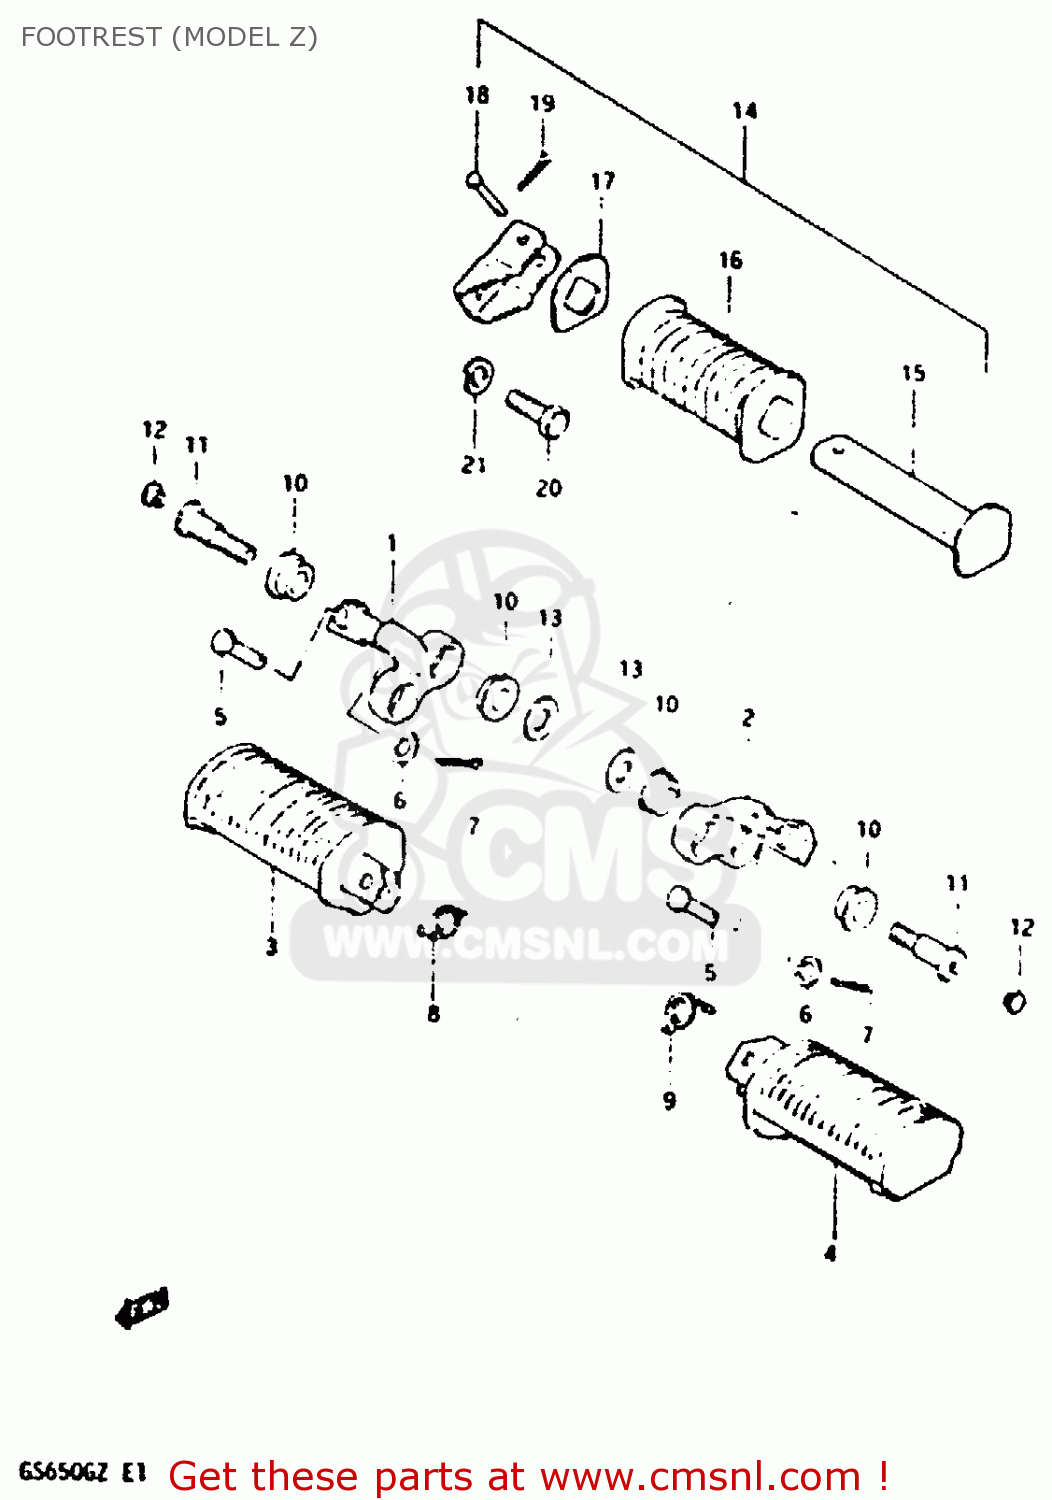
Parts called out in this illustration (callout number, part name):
1	BAR, FOOTREST RH (BLACK)
2	BAR, FOOTREST LH (BLACK)
3	RUBBER,FOOTREST
4	FOOTREST
5	PIN
6	WASHER
7	PIN 20X20
8	SPRING
9	SPRING
10	BUSH
11	BOLT
12	CAP
13	WASHER(10.2X28X2.3)
14	FOOTREST ASSEMBLY,REAR,LEFT
15	BAR,REAR FOOTREST,LEFT
16	RUBBER,PILLION FOOTREST
17	WASHER,PILLION FOOTREST RUBBER
18	PIN
19	PIN 20X20
20	BOLT 10X20
21	LOCK WASHER
